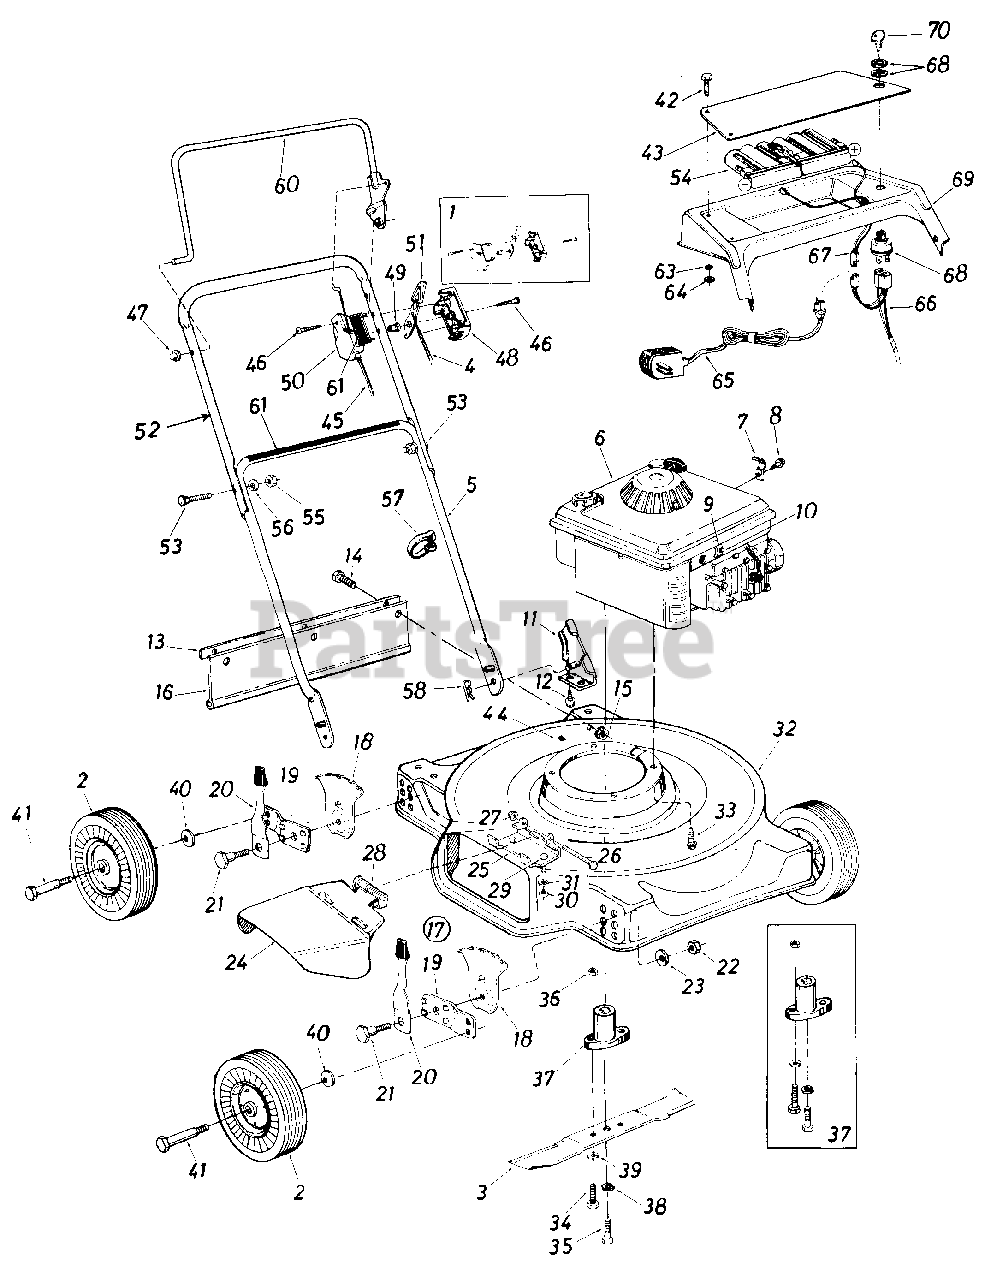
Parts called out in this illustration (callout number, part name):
1	Kit-Control Housing Comp.
2	Wheel Assy.
3	Blade-20"
4	Throttle Control Wire-39"
5	Lower Handle
6	Engine
7	Casing Clamp
8	Hex B-Tap Scr. #10 x .38"
9	Casing Clamp
10	Hex Wash. Hd. AB-Tap Scr. #8 x .38" Lg
11	Handle Mount Brkt.-L.H.
12	Hex Wash. Hd. B-Tap Scr. 5/16-18 x .50" Lg.
13	Retaining Strip
14	Hex Bolt 1/4-20 x .62" Lg.
15	Hex Sems Nut 1/4-20 Thd.
16	Rear Flap Ass'y.
17	Height Adj. Ass'y.-R.H.
18	Height Adj. Plate
19	Pivot Bar
20	Spring Lever w/Knob
21	Shld. Bolt .500" Dia. x .375
22	Hex Nut 3/8-16 Thd.
23	Bell-Wash. .39' I.D. x 1.13" O.D.
24	Chute Deflector Ass'y.- Comp.
25	Deflector Hinge Plate
26	Pivot Pin
27	Cap Speed Nut 1/4" Rod
28	Torsion Spring
29	Hex Bolt 1/4-20 x .50" Lg.
30	Hex Nut 1/4-20 Thd.
31	L-Wash. 1/4" I.D.
34	Hex Bolt 5/16-24 x 1.00" Lg. (Grade 8)
35	Hex Bolt 3/8-24 x 2.25" Lg. (Grade 5)
36	Hex Nut 5/16-24 Thd.
37	Blade Adapter Kit
38	L-Wash. 3/8" I.D. Heavy Duty
39	L-Wash. 5/16" I.D.
40	Bell-Wash. .400" I.D. x .88"O.D.
41	Shld. Bolt .498" Dia. x 1.450" Lg.
42	Fl-Hd. Phil. Scr. #8-32 x .38"
43	Battery Plate
45	Control Cable
46	Truss. Mach. Scr. #12 x 1.50" Lg .
47	Cap Speed Nut 5/16" Rod
48	Control Panel Half
49	Control Disc Pin
50	Clutch Panel Half
51	Throttle Control Lever
52	Upper Handle
53	Curved Carriage Bolt 5/16-18 x 1.75" Lg.
54	Battery Pack
55	Hex Nut 5/16-18 Thd.
56	L-Wash. 5/16" I.D.
57	Cable Tie
58	Internal Cotter Pin
60	Control Handle-R.H.
61	Instruction Labels
63	External L-Wash. #8 I.D.
64	Hex Nut #8-32 Thd.
65	Battery Charger
66	Wire Harness
67	Battery Pack Lead
68	Ignition Switch
69	Handle Panel
70	Ignition Key
